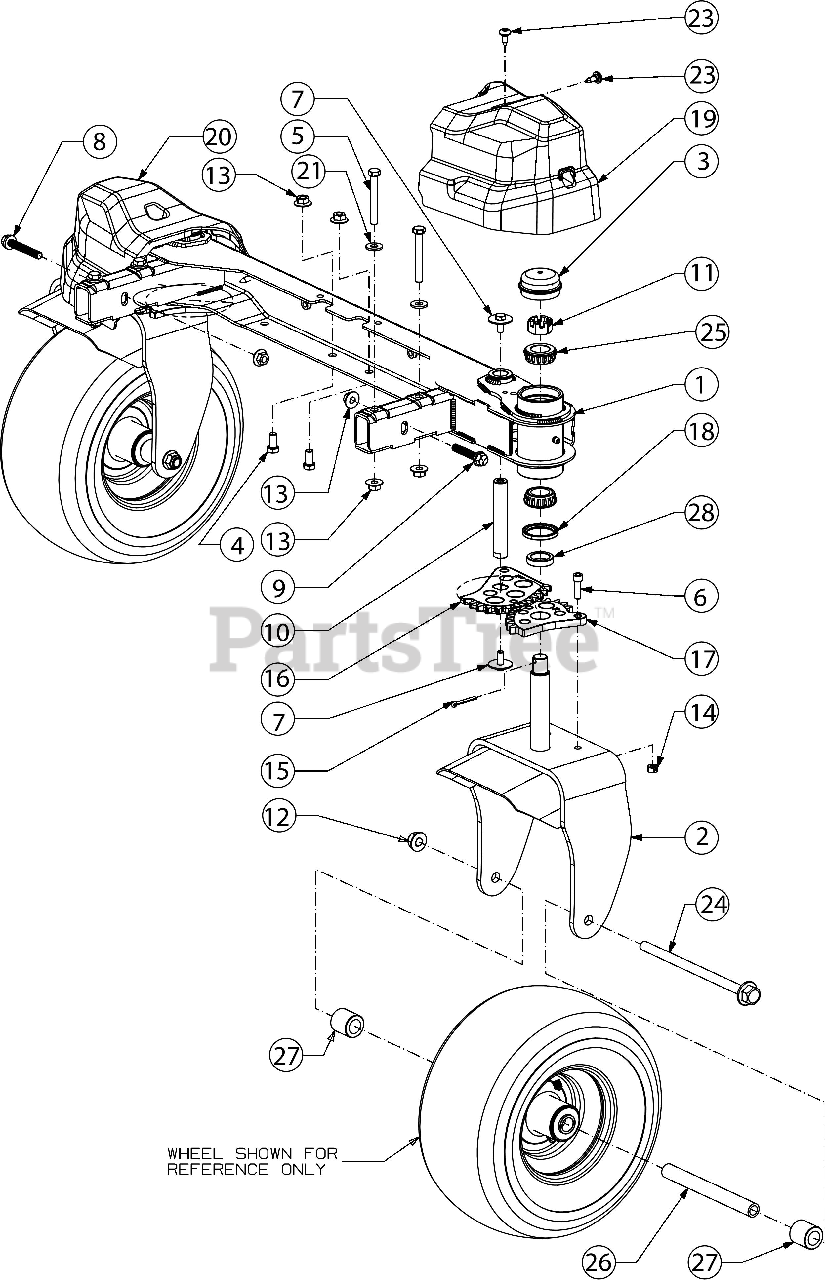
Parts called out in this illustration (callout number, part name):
1	AXLE-FRONT SYNC
1	GREASE FITTING
2	CASTER BRACKET ASSEMBLY
3	AXLE GREASE CAP
4	HEX SCREW 3/8-16 X .75
5	SCREW 3/8-16 X 2.75 GR5
6	SCREW 5/16-18 X 1
7	SCREW 5/16-18 X.75 GR5
8	SCREW 3/8-16 X 2.25 GR5
9	SCREW 3/8-16 X 2.00 GR5
10	STEERING GEAR PIVOT SHAFT
11	HEX NUT CASTLE 3/4-16
13	FLANGE LOCK NUT
14	HEX NUT
15	COTTER PIN-5/32 DIA
16	STEERING GEAR
17	STEERING SPUR GEAR 13T
19	AXLE COVER (RH)
20	AXLE COVER (LH)
21	FLAT WASHER .385X.870X.090
23	TORX SHOULDER SCREW 1/4-20
24	SCREW 1/2-13X8.5 GR5
25	ROLLER BEARING 47MM X 25MM X 15MM
26	CASTER AXLE SPACER
27	SPACER .76X1.23X1.25
